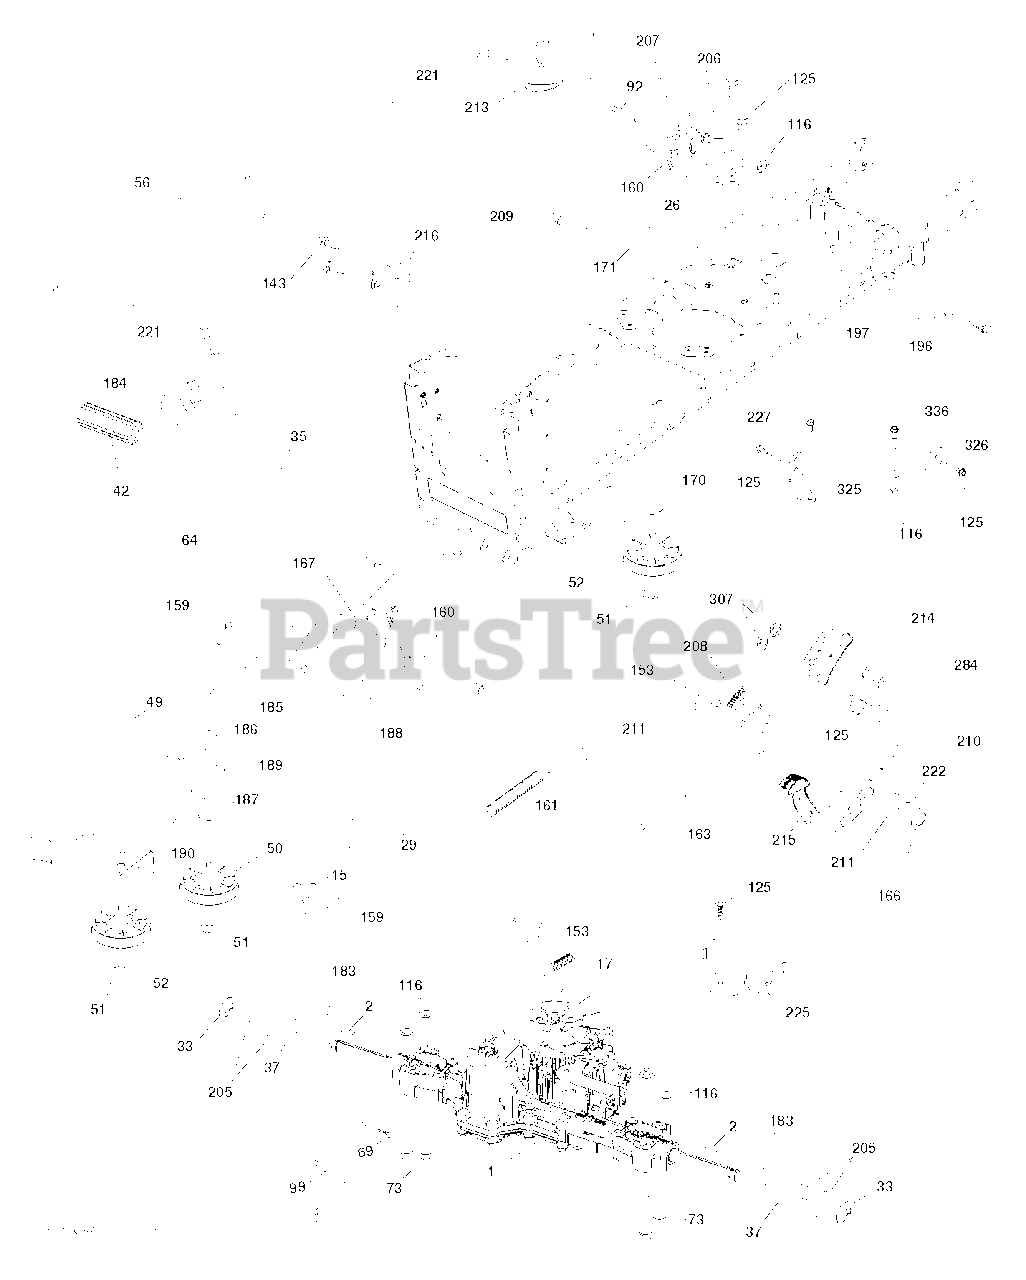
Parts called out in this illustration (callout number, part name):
2	SQUARE KEY
15	WASHER
17	SPRING.BRAKE.K46.GREEN
26	SPRING.RETURN.CRUISE
29	ROD.BRAKE.K46
35	ROD .BRAKE. PARKING. GT. HUSQ.
37	WASHER.HARDENED
42	PEDAL COVER T
50	IDLER.FLAT.910.OFFSET
51	NUT LOCK FLG 3/8-16 UNC
52	IDLER.V-GROOVE.910.OFFSET
56	V-BELT.MOWER.92.40.42/K46
64	SHAFT.ASM.PEDAL.BRK.CNTR
69	HAIRPIN.SOFT.ZINC.059X1.125
92	BOLT
99	ARM.PIVOTING.TCRD.GEN2.5.BAGGE
116	NUT LOCK HEX FLANGE 5/16-18
125	SCREW
143	SCREW LT
153	RETAINER M
159	COTTER PIN
160	RETAINER CLIP
161	SPRING, RETURN LT
163	ROD.CONTROL.K57R.K46
166	NUT.PUSH.625
167	LATCH.BRAKE.SPRING
170	KEEPER.V-IDLER.CENTER.
183	SPACER AXLE
184	HANDLE.PARKING.BRAKE.H (BLK)
186	SPACER.RETAINER
187	WASHER 12/32X2X10GA
188	RP LINK.CLUTCH.GROUND.DRIVE
189	BELLCRANK.GROUND.DRIVE.TEX.
190	KEEPER.BELLCRANK.DRIVE
196	SCREW 3/8-16X1
197	CLUTCH.ANTIROTATION.WIREFORM.
206	BRACKET.MOUNT.CRUISE.LATCH
207	LATCH.CONTROL.CRUISE.TEX
208	GEAR.SECTOR.CONTROL.CR
209	ROD.CONTROL.CRUISE.GT.
210	ROCKER.ASM.PEDAL.CONTR
211	BEARING.NYLON
213	KNOB.CONTROL.CRUSIE.HU
214	PEDAL.FORWARD.HUSQVARNA.DEALER
215	PEDAL.COVER.REVERSE.CRD.X428BK
216	BRACKET.PULLEY.IDLER.W/TEX
221	RETAINER.SPRING.CLIP.H
222	WASHER 21/32 X 1-1/4 X 10 GA.
225	KEEPER.BELT.TRANSAXLE.K46
227	SCREW
284	NUT.U-CHNL.1/4-20.550DP.350PNL
307	SCREW.MACHINE.CR.1/4-20
325	BRACKET.TRQ.STP.46.20".TIRE.LH
326	BRCKT.PNT.TRQ.STP.46.20TIRE.RH
336	BOLT.5/16-18X1-3/4.FLANGED.HEX
